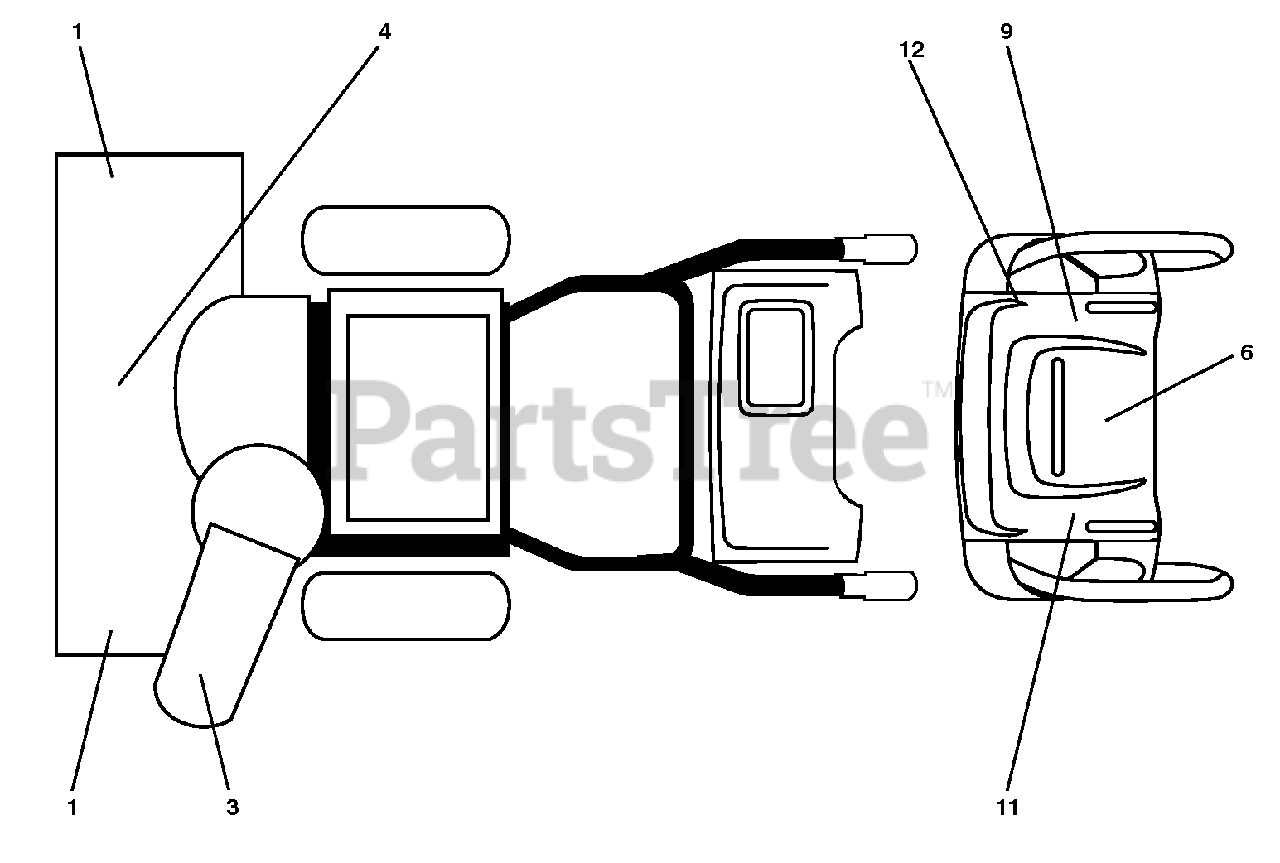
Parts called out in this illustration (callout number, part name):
1	DECAL.SNOWTHR.AUGER
3	DECAL.SNOWTHR.CHUTE.SAFETY
4	DECAL.SNOWTR.READ.OWN.MAN.E/F
6	DECAL.CONSOLE.SNOW.INST.ENG/FR
9	DECAL.CONS.RH.INST.GRY
11	DECAL.CONS.LH.REMOTE.INST.GRY
12	DECAL.CONSOLE.HAND.WARMER
